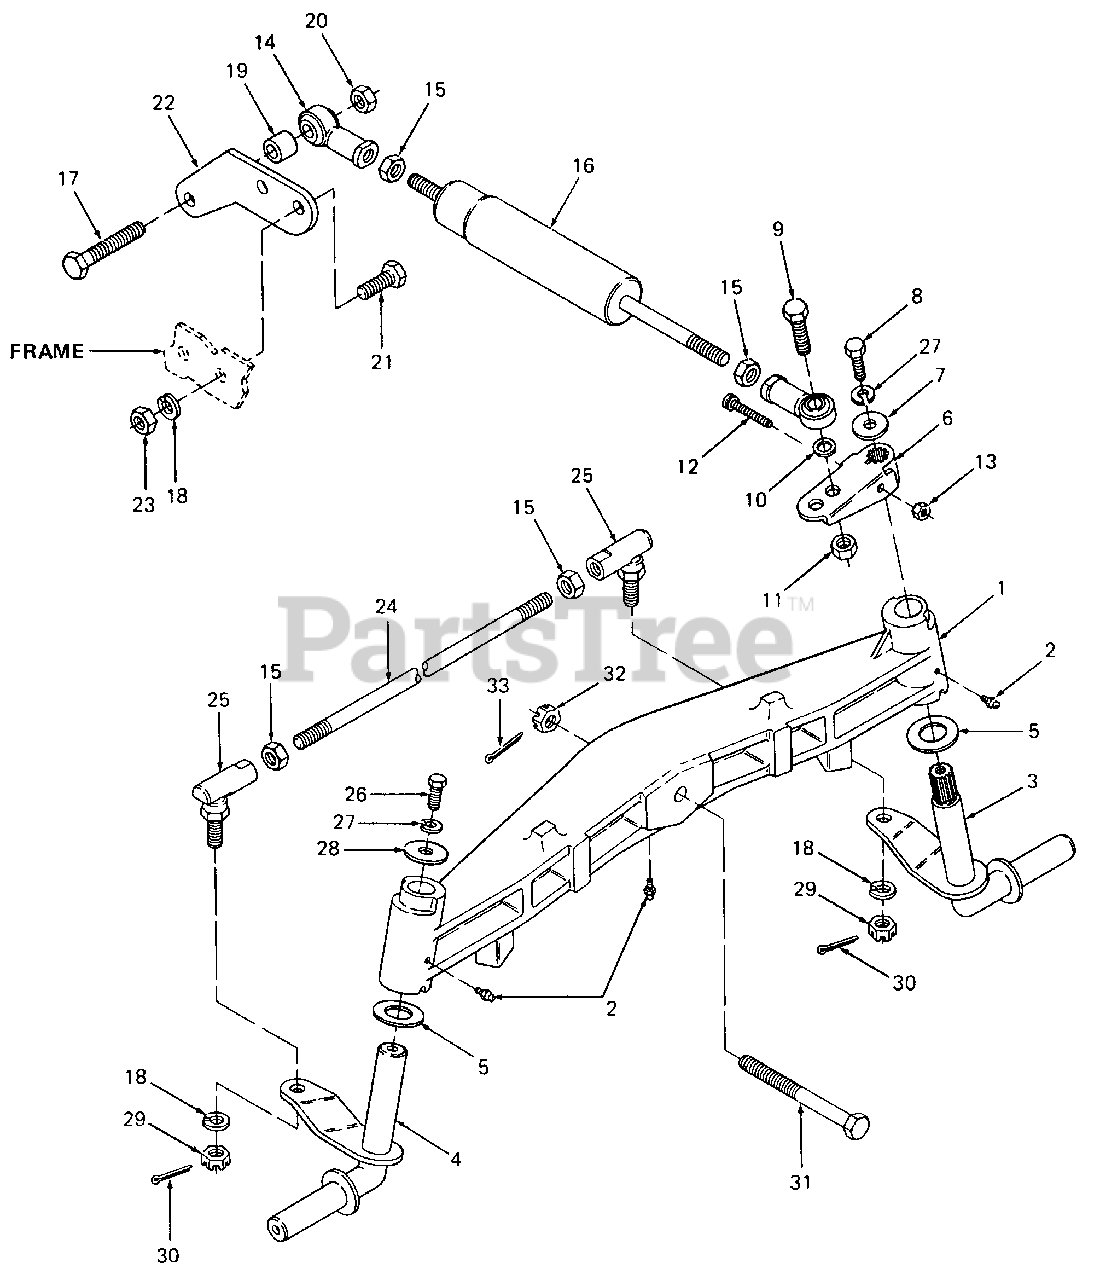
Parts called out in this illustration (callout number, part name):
3	Knuckle, Steering - LH
4	Knuckle, Steering - RH
5	Washer, Thrust, 1.03 X 1.62 X .03 Thk HDN
8	Screw, Hex Cap, 3/8-24 X 1.0 Lg
9	Bolt, Hex, 1/2-20 X 1.5 Lg GR5
10	Washer, Flat, .531 X .688 X .054 Thk
11	Nut, Hex Top Lock, 1/2-20
12	Screw, Socket Hd Cap, 1/4-20 X 2.0 Lg
13	Nut, Hex Patch Lock, 1/4-20
14	Alignaball End, 1/2-20
15	Nut, Hex Jam, 1/2-20 GR5
18	Washer, Lock, 1/2
19	Spacer, .505 X .75 X .780 Lg
20	Nut, Hex Center Lock, 1/2-13 GR5
21	Screw, Hex Cap, 1/2-13 X 1.25 Lg GR5
22	Bracket, Power Steering Mtg
23	Nut, Hex, 1/2-13 GR5
25	Ball Joint
26	Screw, Hex Cap, 3/8-24 X 1.0 Lg
27	Washer, Lock, 3/8
28	Washer, Flat, .406 X 1.5 X .12 Thk
29	Nut, Hex Castle, 1/2-20 GR5
30	Pin, Cotter, 3/32 Dia X 1.25 Lg
31	Bolt, Hex, 3/4-10 X 5.25 Lg GR5
32	Nut, Hex Castle, 3/4-10
33	Pin, Cotter, 1/8 Dia X 1.5 Lg
